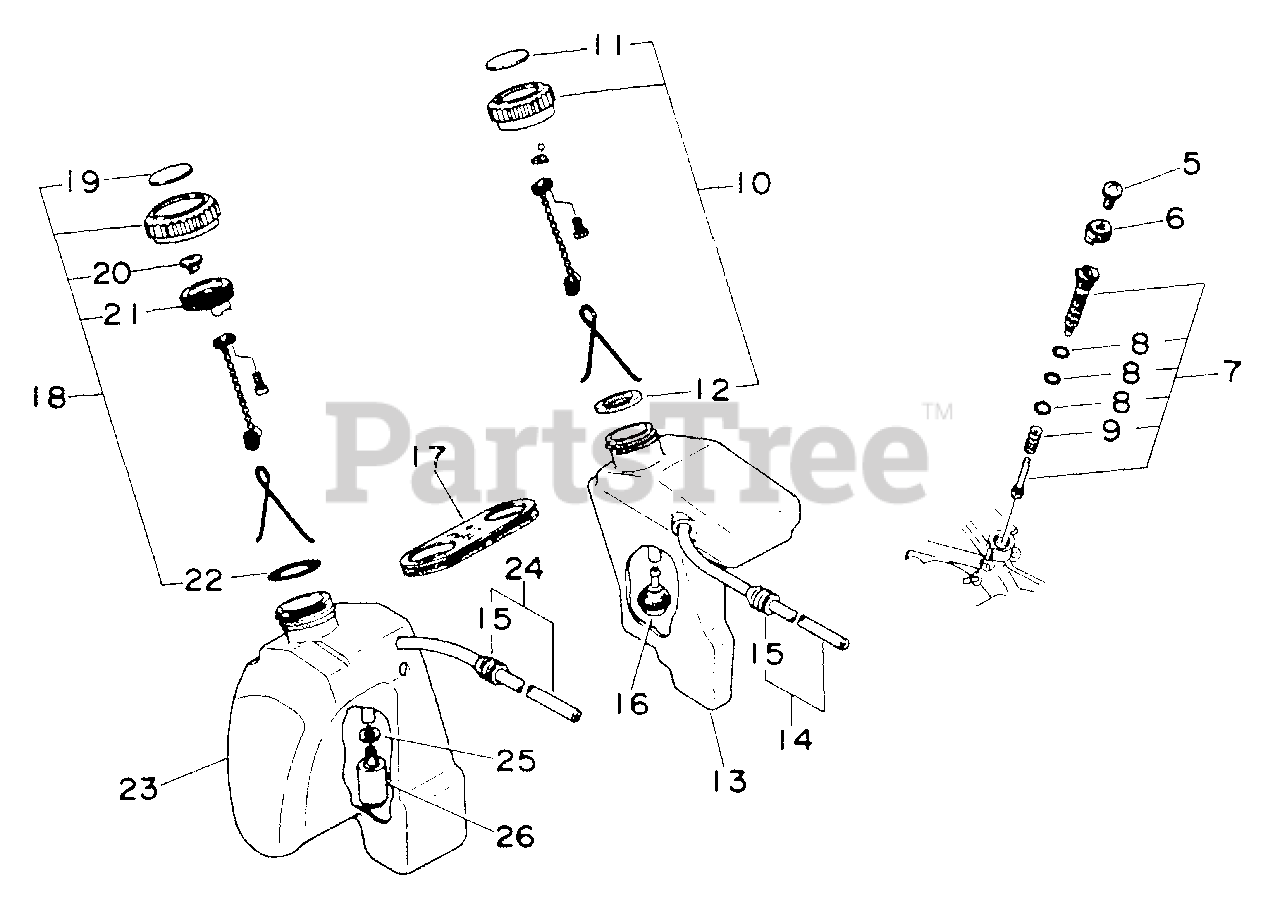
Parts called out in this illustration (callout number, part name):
5	SCREW 5×10
6	WASHER, LOCK
7	AUTO-OILER ASSY
10	CAP ASSY
11	LABEL - CHAIN OIL
12	GASKET, CAP
13	TANK, OIL
14	PIPE, OIL
16	FILTER, OIL
17	CONNECTOR
18	CAP ASSY
19	LABEL - FUEL MIX
20	VALVE, CHECK
21	HOLDER, CHECK VALVE
22	O-RING 22
23	TANK, FUEL
24	PIPE
25	WASHER 5.5×12×0.8
26	FILTER, FUEL
